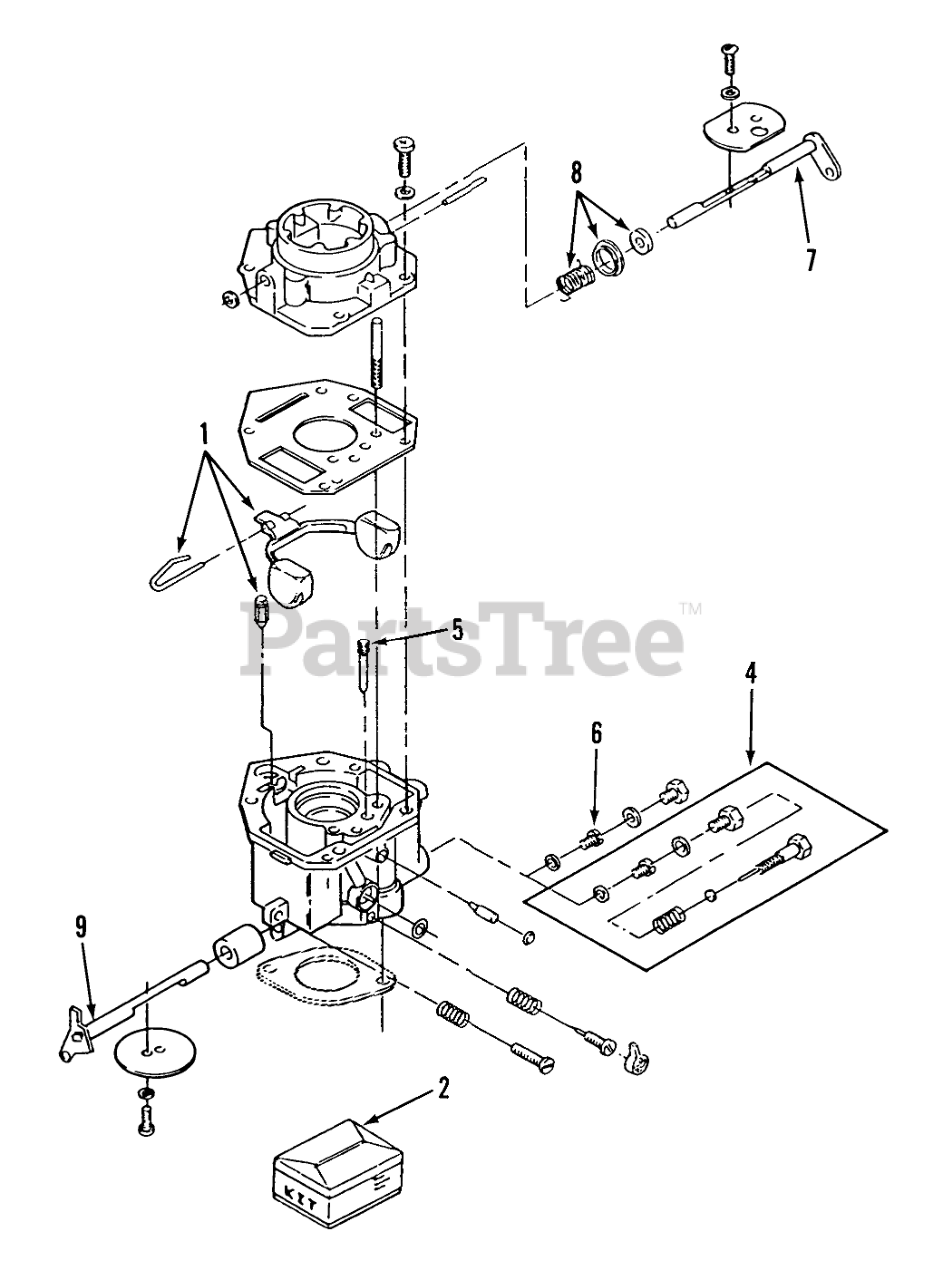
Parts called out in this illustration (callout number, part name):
1	Flat Kit (Includes Float Pin)
2	Repair Kit (Includes Screw and Plug Package, Gasket Package, Float Valve, Idle Adjustment Needle and Spring, Mounting Gaskets, Idle Limit Cap)
4	Variable Jet Kit-Optbnal (High Altitude Application Includes Power Jet and Gasket, Retainer, Power Needle Spring, Power Needle and Power Plug Gasket)
5	Idle Jet
6	POWER JET
7	Choke Shaft Kit (Includes Choke Valve, Valve Set Screw and Air Filter)
8	Choke Lever Kit (Includes Choke Lever Ring, Choke Spring and Choke Collar)
9	Throttle Shaft Kit (Includes Valve Set Screw, Air Filter and Throttle Valve)
